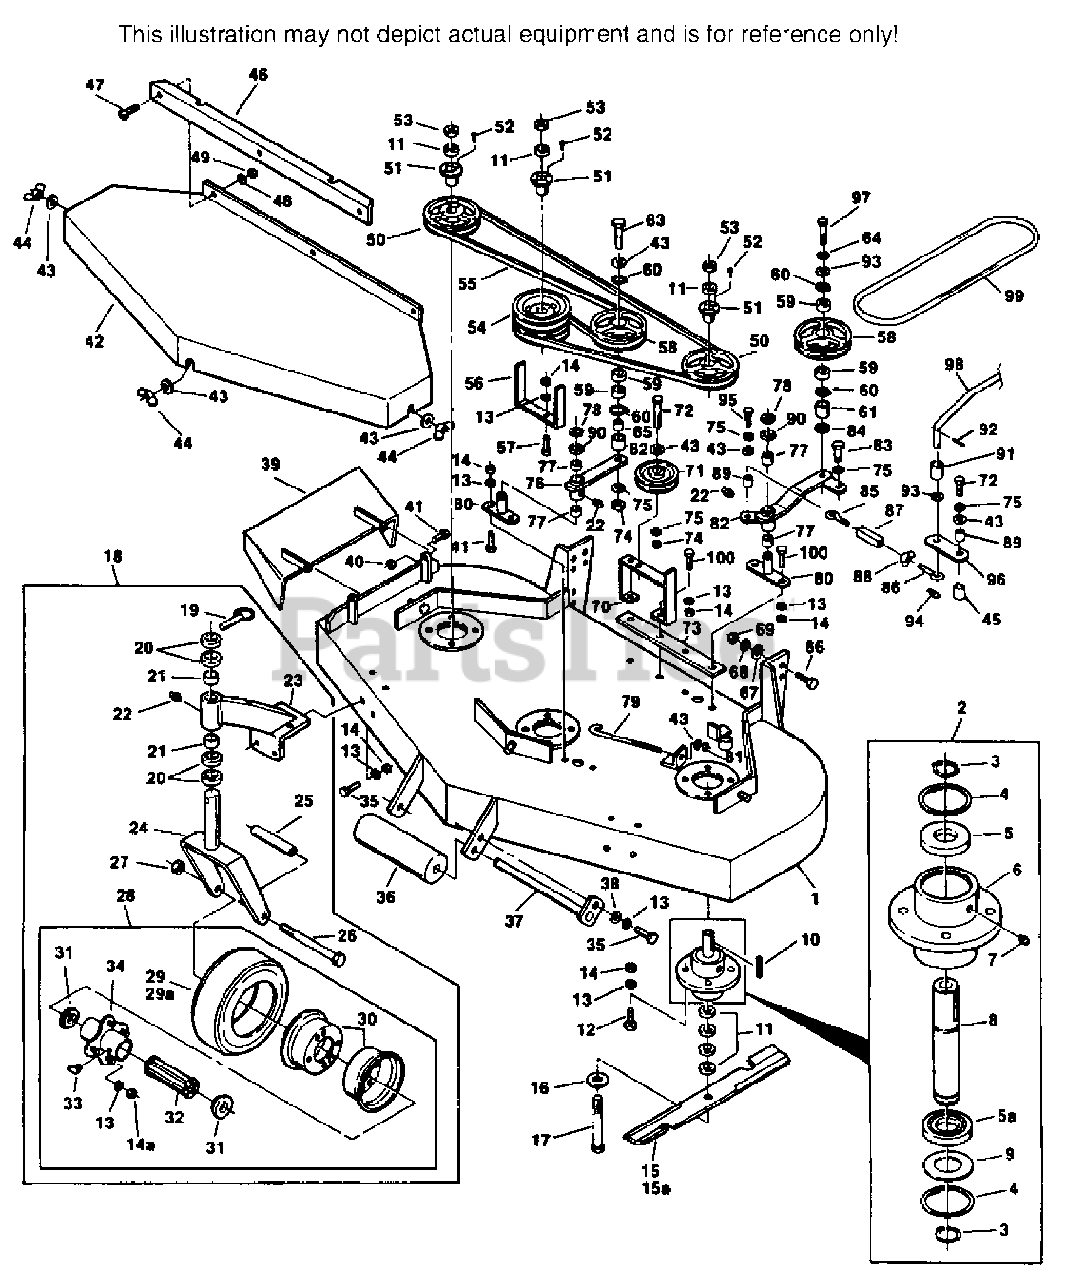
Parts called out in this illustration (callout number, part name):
1	CUTTER DECK WLD(INCL. DECAL)
2	CUTTER SPINDLE ASSY.(INCL. 3-9)
3	RETAINING RING, 1" EXT.-INVERTED
4	RETAINING RING, 2-7/16 INT.-BASIC
5	BEARING, CUTTER SPINDLE UPPER
5A	BEARING, CUTTER SPINDLE LOWER
6	SPINDLE HOUSING
7	GREASE FITTING, STR. 5/16 SERR.
8	SPINDLE, CUTTER BLADE
9	WASHER, 1-15/16 X 2-13/32 X 16GA.
10	KEY, 1/4 X 1/4 X 2
11	SPACER, CUTTER BLADE
15	CUTTER BLADE, 16-1/2" STD.
15A	CUTTER BLADE, 16-1/2" HIGH LIFT
16	FLAT WASHER, 5/8W
17	HEX HEAD BOLT, 5/8-11 X 9-1/2
18	CASTER ASSY, COMP.(INCL. 19-28)
19	QUICK PIN
20	SPACER, CASTER YOKE, 1/2 LONG
21	BRONZE BEARING
22	GREASE FITTING, STR, 1/4-28
23	SUPPORT ASSY.(INC. 21-22)
24	CASTER YOKE WLD.
25	SLEEVE, CASTER WHEEL BEARING
26	HEX HEAD BOLT, 1/2-13 X 5-1/2
28	WHEEL ASSY.(INCL. 13-14, 29-34)
29	TIRE ONLY, CASTER WHEEL
29A	INNER TUBE ONLY, CASTER WHEEL
30	RIM PAIR, CASTER WHEEL
31	RETAINER, BEARING, CASTER WHEEL
32	ROLLER BEARING, CASTER WHEEL
33	GREASE FITTING, 45 1/4-28
34	HUB ASSY. W/BOLTS, CASTER WHEEL
39	DISCHARGE CHUTE WLD.
40	HEX NUT, 5/16-18 ELASTIC STOP
42	BELT COVER ASSY.(INCL. DECALS)
43	WASHER, 25/64 X 15/16 X 12 GA.
44	WING NUT, 3/8-16
45	SPINDLE SHIELD
46	BELT COVER SKIRT
47	MACH SCREW, 1/4-20 X 1/2 TRUSS HD.
50	PULLEY(INCL. 51-52)
51	TAPER HUB
54	PULLEY, DOUBLE(INCL. 51-52)
55	BELT, BLADE DRIVE
56	BELT GUIDE
58	PULLEY IDLER
59	BEARING
60	RETAINING RING, 1-9/16 INT. BASIC
61	SLEEVE, IDLER BEARING
62	SPACER, IDLER BEARING
65	SLEEVE, IDLER PULLEY
67	WASHER, 15/32 X 59/64 X 16 GA.
69	HEX NUT, 7/16-14, ELASTIC STOP
70	IDLER PULLEY SUPPORT
71	PULLEY, BELT GUIDE
73	WASHER, 13/32 X 13/16 X 16 GA.
76	IDLER ARM ASSY.(INCL. 22 & 77)
77	BRONZE BEARING
78	RETAINING RING, 3/4 EXT.-"E"
79	ROD, IDLER PULL, J
80	IDLER PIVOT WLD.
81	HEX NUT, 3/8-16 ELASTIC STOP
82	IDLER ARM ASSY.(INCL. 22 & 77)
83	SHOULDER BOLT
84	SPACER, IDLER
85	EYEBOLT, LH
86	EYEBOLT, RH
87	TURNBUCKLE
88	WING NUT, 5/16-18
89	SLEEVE, CAM CLUTCH
90	WASHER 49/64 X 1 1/4 X 16 GA.
91	SLEEVE, CLUTCH ROD
93	WASHER, 33/64 X 1 X 16 GA.
94	HAIR PIN, LARGE
96	CAM LINK
97	HEX HD. BOLT, 1/2-20 X 2
